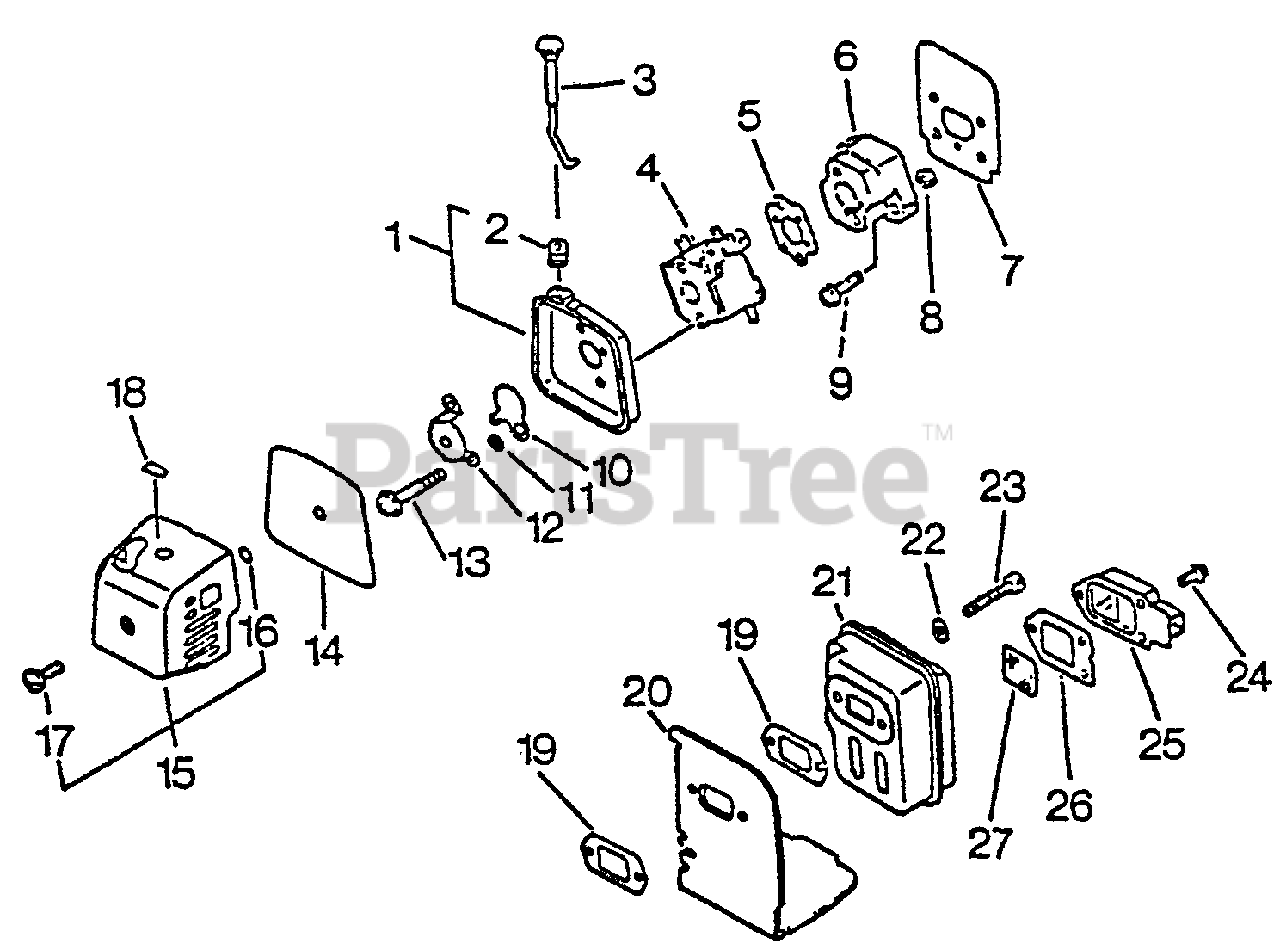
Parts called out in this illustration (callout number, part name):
1	CASE, AIR FILTER
3	ROD, CHOKE
4	CARBURETOR C1U-K16
5	GASKET, INTAKE
6	INSULATOR, INTAKE
7	SHIELD, INTAKE
9	SCREW - 5X20
10	SHUTTER, CHOKE
11	WASHER - 5
12	BRACKET, AIR CLEANER
13	SCREW - 5X57
14	FILTER, AIR
15	COVER, AIR FILTER
16	O-RING - 4
18	LABEL - CHOKE
19	GASKET, EXHAUST
20	COVER, EXHAUST
21	MUFFLER ASSY
22	WASHER - 5
23	SCREW - 5X55
24	SCREW - 4X10
25	GUIDE, EXHAUST - OUTER
26	GASKET, EXHAUST
27	SCREEN, SPARK ARRESTOR
